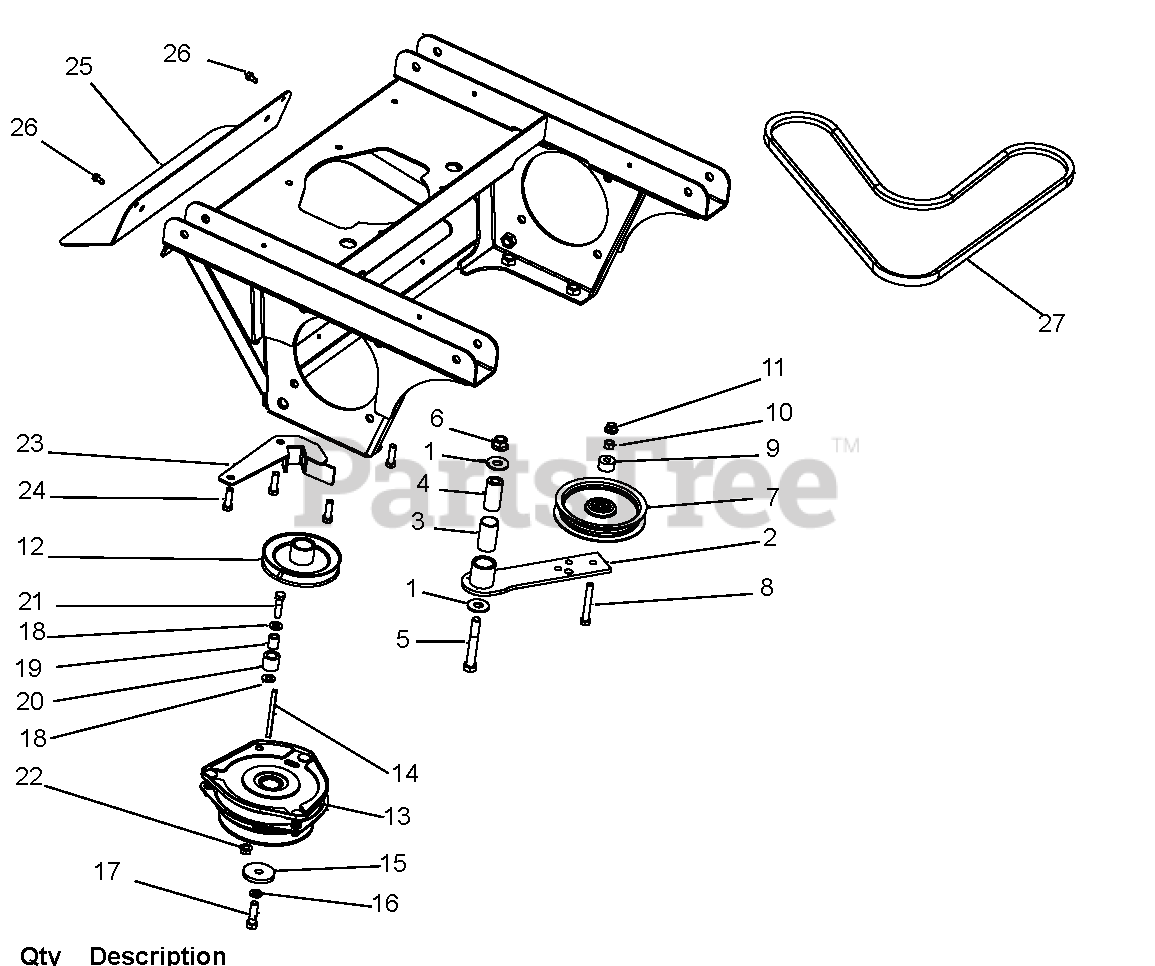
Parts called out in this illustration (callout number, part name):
1	Washer, Flat Steel.563 x 1.38 x .109YWZC
2	Weldment, Idler Arm Ground Drive
3	Bushing, 1.00 x 1.125 x 1.937
4	Bushing, Spacer .502 x .997 x 2.03 PM
5	Bolt, Hex .50-13 x 3.50 GR5 YWZC
6	Nut, Locking Nylon-Flange .50-13 YWZC
7	Idler, Flat 5.00 x .38
8	Bolt, Hex .38-16 x 2.75 GR5 YWZC
9	Spacer .390 x 1.000 x .562
10	Nut, Locking Center .38-16 YWZC
11	Nut, Locking Nylon-Flange .38-16 YWZC
12	Sheave, Engine 5.426 x 1.127
13	Clutch, Electric-OGURA GT3.5-VP01R
14	Key, Square .25 x 3.50 x .25 SAE
15	Washer, Flat Steel .469 x 2.00 x .25 YWZC
16	Washer, Lock .44 x .109 REG YWZC
17	Bolt, Hex .44-20 x 1.50 G5 YZ EP80
18	Washer, Flat Steel.406 x .812 x .065 YWZ
19	Bushing, S.407 x .625 x .813 ST
20	Bumper, Rubber .62 x 1.0 x .88 LG
21	Bolt, Hex .38-16 x 1.50 GR5 YWZC
22	Nut, Locking Top-Flange .38-16 YWZC
23	Weldment, Clutch Stop
24	Bolt, Hex .38-16 x 1.25 FTHG5 EP30YZ
25	Shield, Muffler Heat
26	Screw, Tap .25-20 x .50 Hex Washer Head TR YWZ
27	V-Belt, Cogged B-Raw Edge
